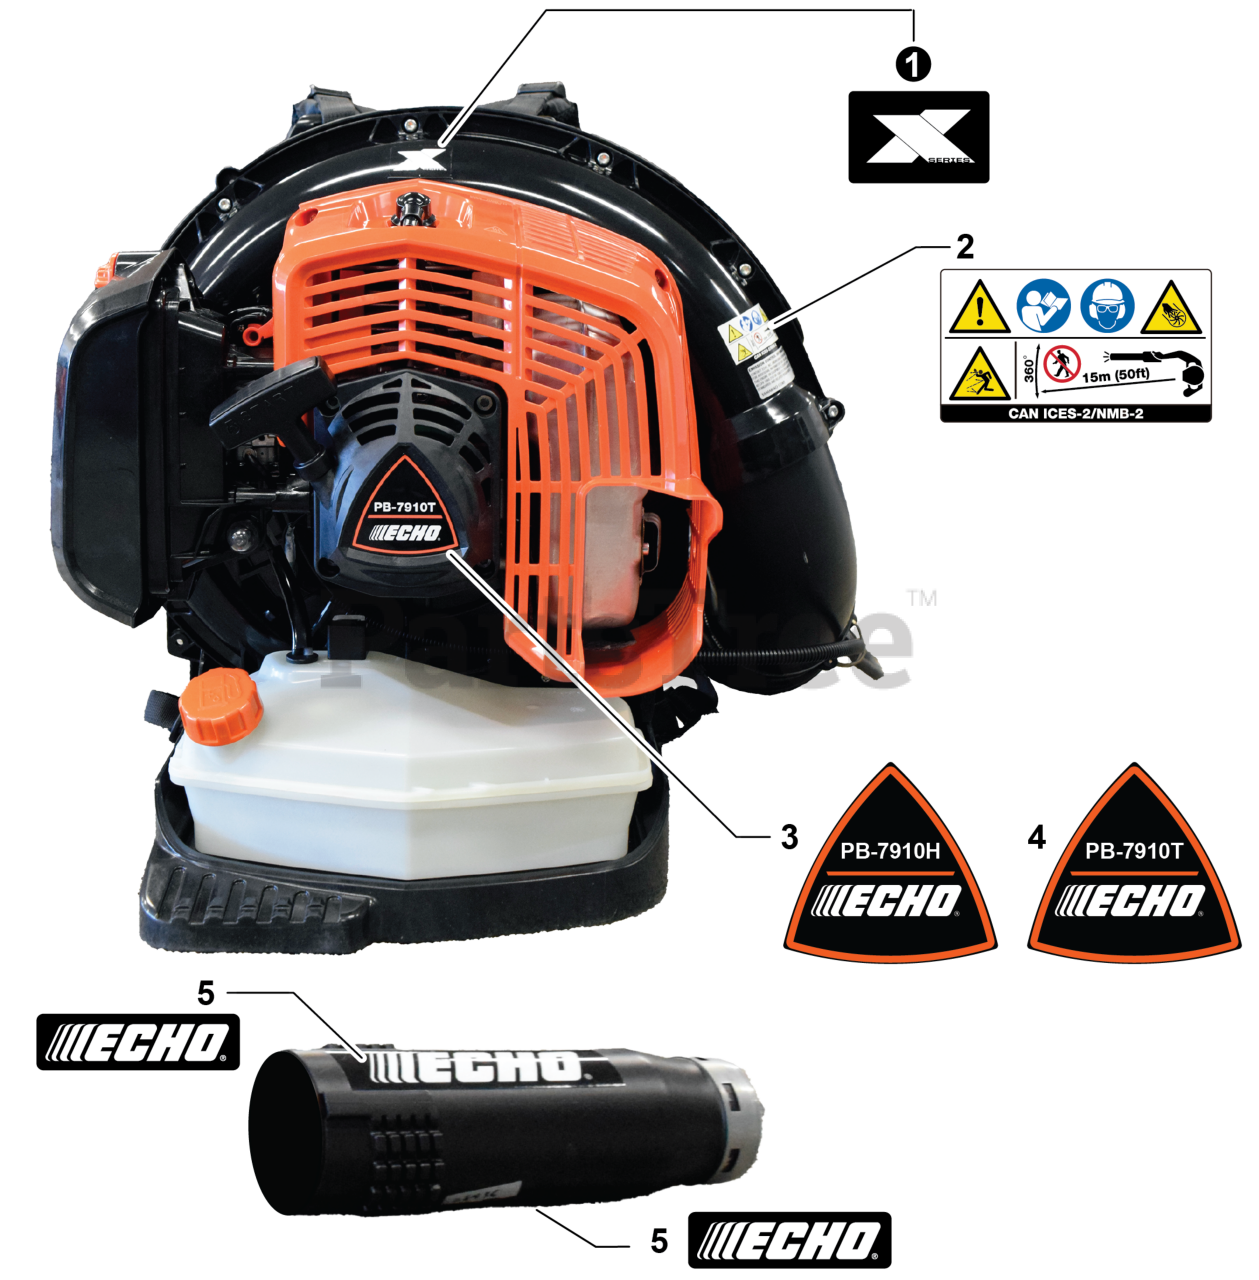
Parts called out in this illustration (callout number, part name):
1	LABEL, X-SERIES
2	LABEL - CAUTION
3	LABEL - RECOIL STARTER PB-7910H
4	LABEL - RECOIL STARTER PB-7910T
5	LABEL - ECHO
